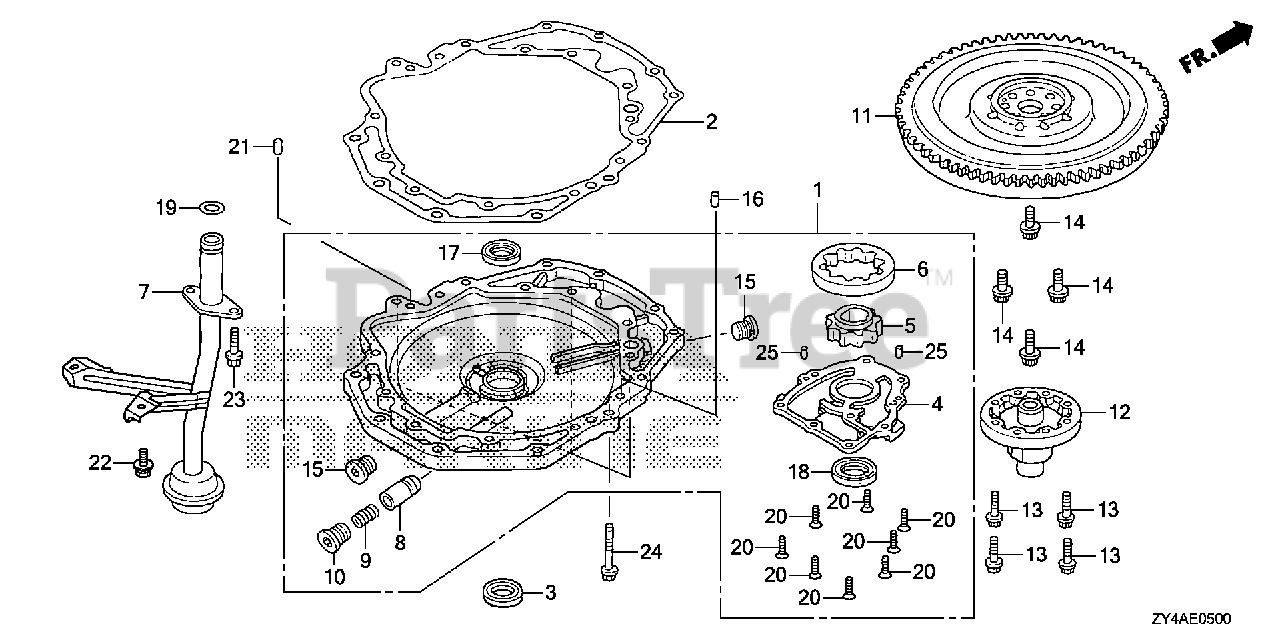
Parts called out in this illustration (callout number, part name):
1	PUMP ASSY., OIL *NH8* (DARK GRAY)
2	GASKET, OIL PUMP BODY
3	RUBBER, OIL PUMP
4	COVER, OIL PUMP
5	ROTOR, OIL PUMP (INNER)
6	ROTOR, OIL PUMP (OUTER)
7	STRAINER, OIL
8	VALVE, RELIEF
9	SPRING, RELIEF VALVE
10	BOLT, SEALING (18MM)
11	FLYWHEEL *TBLACK* (BLACK)
12	BOSS, FLYWHEEL
13	BOLT, SPECIAL (8MM)
14	BOLT, FLANGE (12MM)
15	BOLT, SEALING (22MM)
16	PIN, DOWEL (14X15)
17	OIL SEAL (46X60X9)
18	OIL SEAL (31X46X7) (NOK)
19	O-RING (20.6X2.6)
20	SCREW, FLAT (6X16)
21	PIN B, DOWEL (10X16)
22	BOLT, FLANGE (6X14)
23	BOLT, FLANGE (6X18)
24	BOLT, FLANGE (8X30)
25	ROLLER (5X8)
